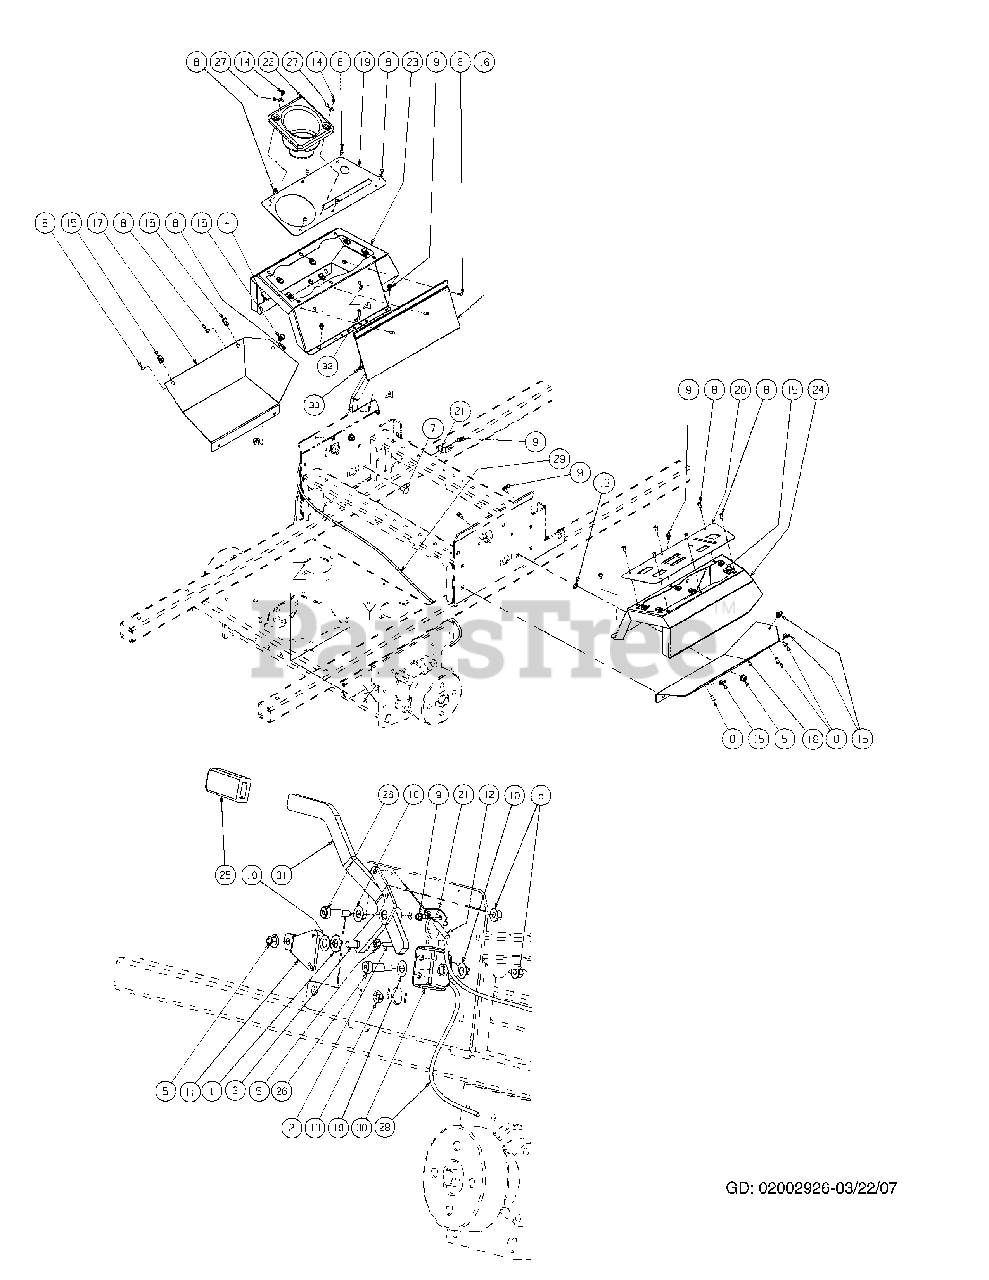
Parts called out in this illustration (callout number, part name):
1	Washer, 1/2 Zinc
2	Carriage Bolt, 3/8-16, 1.00
3	Shoulder Bolt, 1/2 x 1/2
4	Lock Nut, Nylon Insert, 10-32
5	Flange Lock Hex Nut, 3/8-16
6	Phillips Head Machine Screw, 10-32 x 5/8
7	Carriage Bolt, 3/8-16 x .75
8	Screw Button Head, 1/4-20 x .5
9	Screw, TT, 1/4-20, 0.5, Hex Index Washer
10	Washer, .508 ID x 1.0 OD x .020
11	Centering Bracket
12	Left Hand Brake Cable
13	Push Retainer, 3/8
14	Screw, #10-32 x 0.500
15	U-Nut, 1/4-20
16	Bag, Debris Storage
17	Lower Panel, LH
18	Lower Panel, RH
19	Control Panel Cover, LH
20	Control Panel Cover, RH
21	Brake Cable Mounting Bracket
22	Cup Holder
23	Control Panel, LH
24	Control Panel, RH
25	Parking Brake Grip
26	Shoulder Bolt, 1/2 x 1.00, 3/8-16
27	Washer, 3/16
28	Brake Cable, LH
29	Brake Cable, RH
30	Brake Cable Bracket
31	Brake Lever
32	Screw, Hex, Cap, 1/4-20 x .75
33	Lock Nut, 1/4-20
